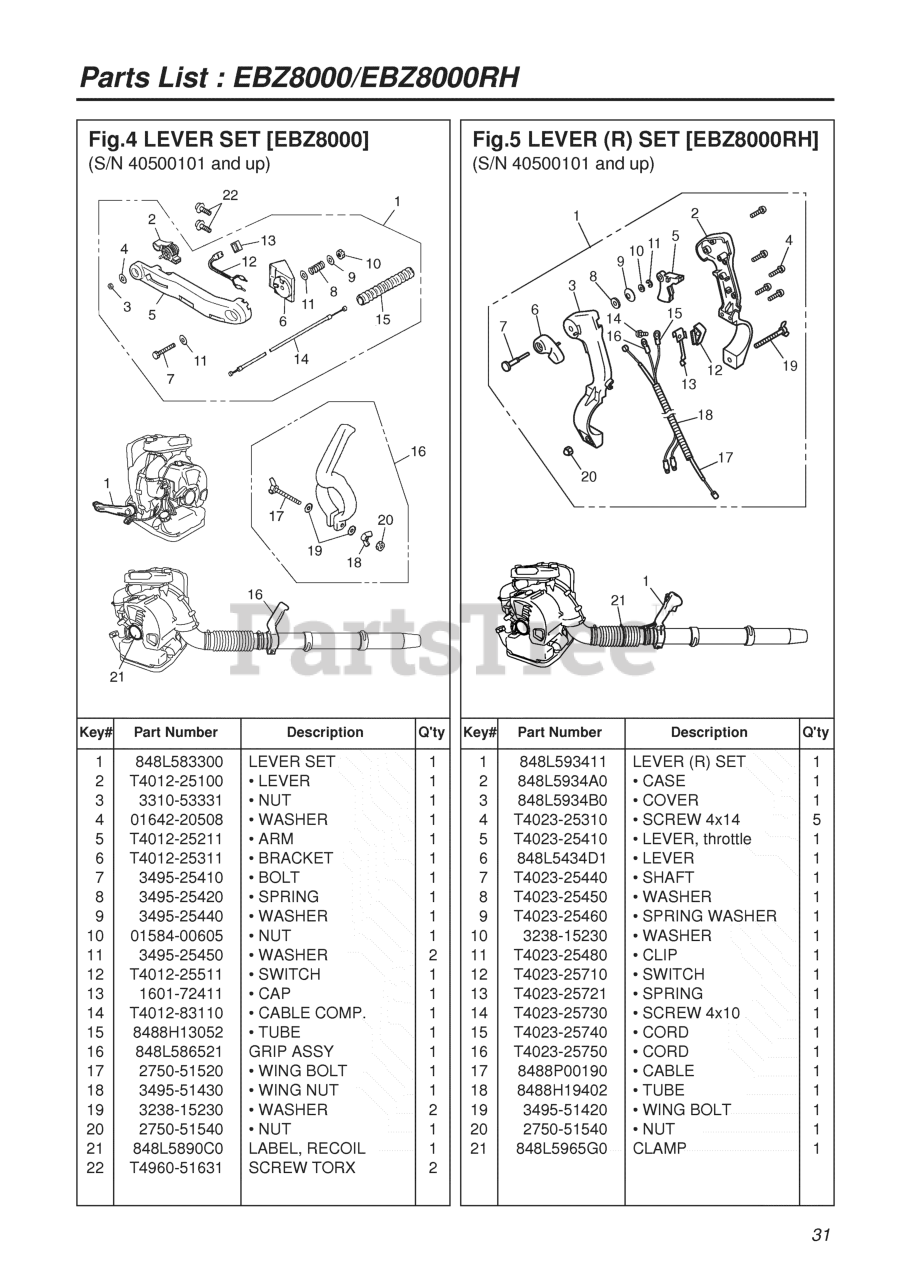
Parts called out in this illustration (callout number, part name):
1	LEVER SET (RPLS. T4012-25001)
2	LEVER
3	NUT (B)
4	WASHER, M5x.8(RPLS 01624-20508
5	ARM (RPLS T4012-25210)
6	BRACKET (RPLS -25310)
7	BOLT
8	SPRING
9	WASHER
10	NUT, M6 X 5
11	WASHER, FLAT
12	SWITCH (RPLS T4012-25510)
13	CAP SWITCH
14	CABLE COMP
15	TUBE (REPLACES T4012-25610)
16	GRIP ASSY
17	WING BOLT
18	NUT, WING
19	WASHER
20	NUT
21	LABEL,RECOIL
22	SCREW TORX
